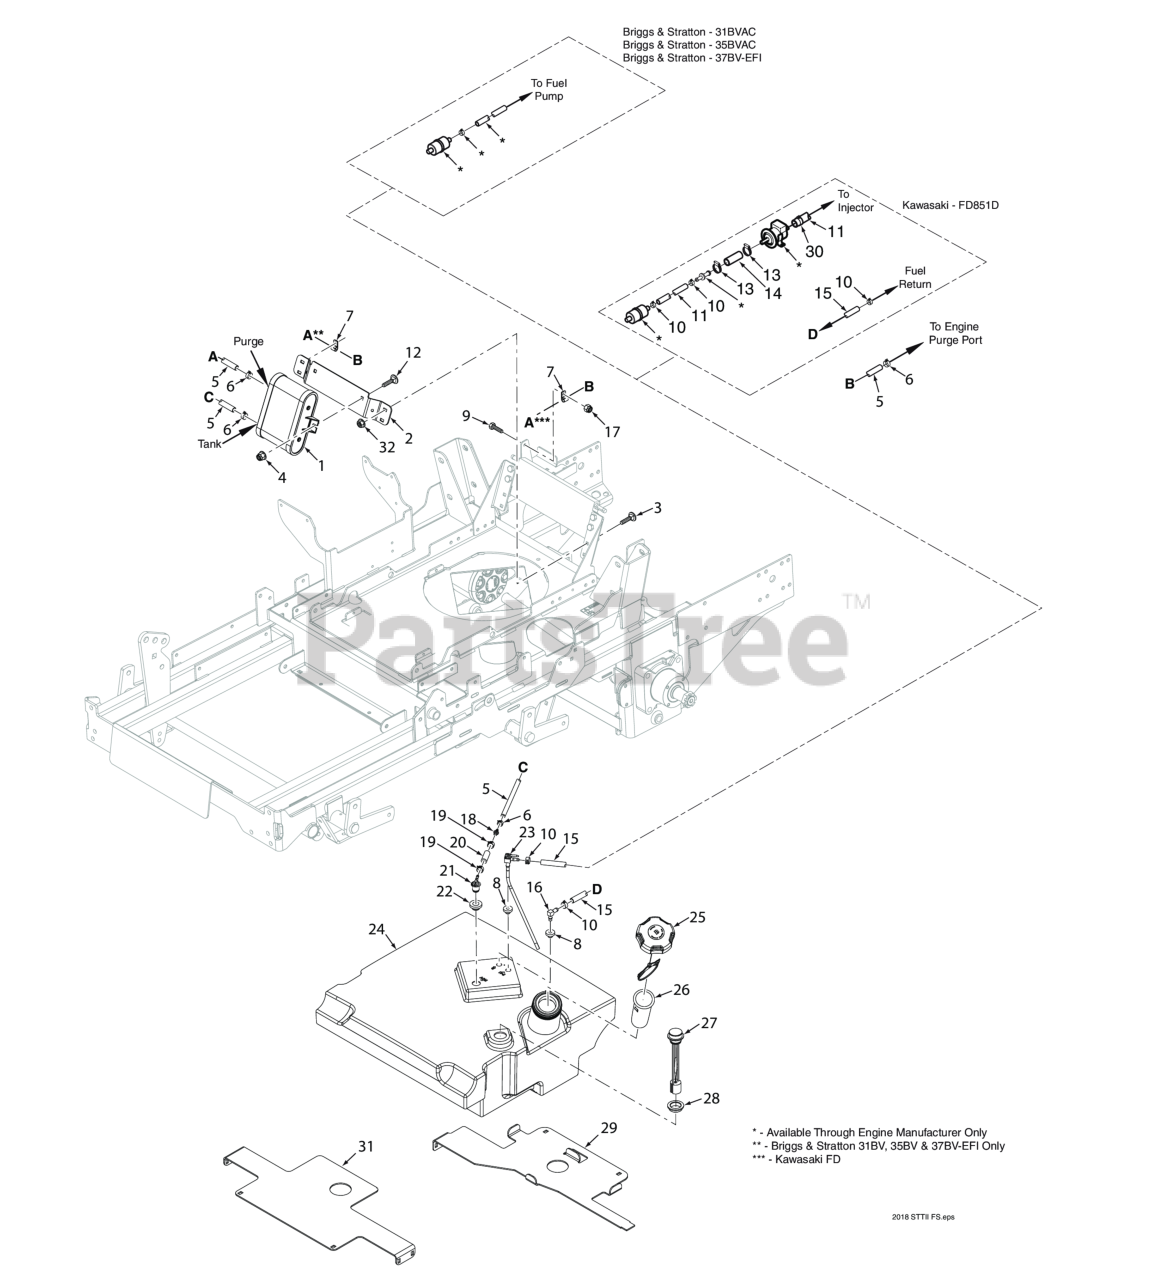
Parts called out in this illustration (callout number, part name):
1	Canister, 1.0 Liter
2	Bracket, Carbon Canister
3	Serr. Fl. Hex Head CPSCR, 1/4-20 x 3/4"
4	Nut, Flange Head Elastic Stop 5/16-18
5	Hose, Vapor Recovery 3/16" (order by inch)
6	Clamp, Vapor Recovery Hose 3/16"
7	Clamp, Cable - .375 Dia.
8	Bushing, 0.56" Dia. Viton
9	Capscrew, Hex Head 1/4-20 x 1"
10	Clamp, Fuel Hose 1/4" Hose I.D.
11	Fuel Hose, 5/16" I.D. Non-Perm (791DFI) - Order by Inch
12	Bolt, 5/16-18 x .75 RHSN Carriage
13	Clamp, Cable 3/4" I.D.
14	Fuel Hose, 1/2" I.D. Non-Perm - Order by Inch
15	Fuel Hose, 1/4" I.D. Non-Perm (791DFI Fuel Return) - Order by Inch
16	Return Fitting
17	Nut, Flanged Elastic Stop 1/4-20
18	Mender, 1/4 x 3/16 w/0.02 Hole
19	CLAMP, FUEL HOSE(KAWASAKI ONLY)
20	Hose, 1/4" Vapor Recovery (order by inch)
21	Remote Vent, No Valve
22	Grommet, Viton,
23	Valve, Fuel Shutoff
24	Fuel Tank Assy. - Kawasaki DFI
25	Fuel Cap w/ Tether (E.P.A.)
26	Tube, Fuel Tank Insert - 6"
27	Fuel Guage Assy., 8"
28	Grommet, Fuel Gauge
29	Rear Support, Fuel Tank
30	Clamp, .69" Max. / .25" Min. Dia.
31	Front Support, Fuel Tank
32	NUT, 1/4-20 SERRATED FLANGE HEX HEAD
